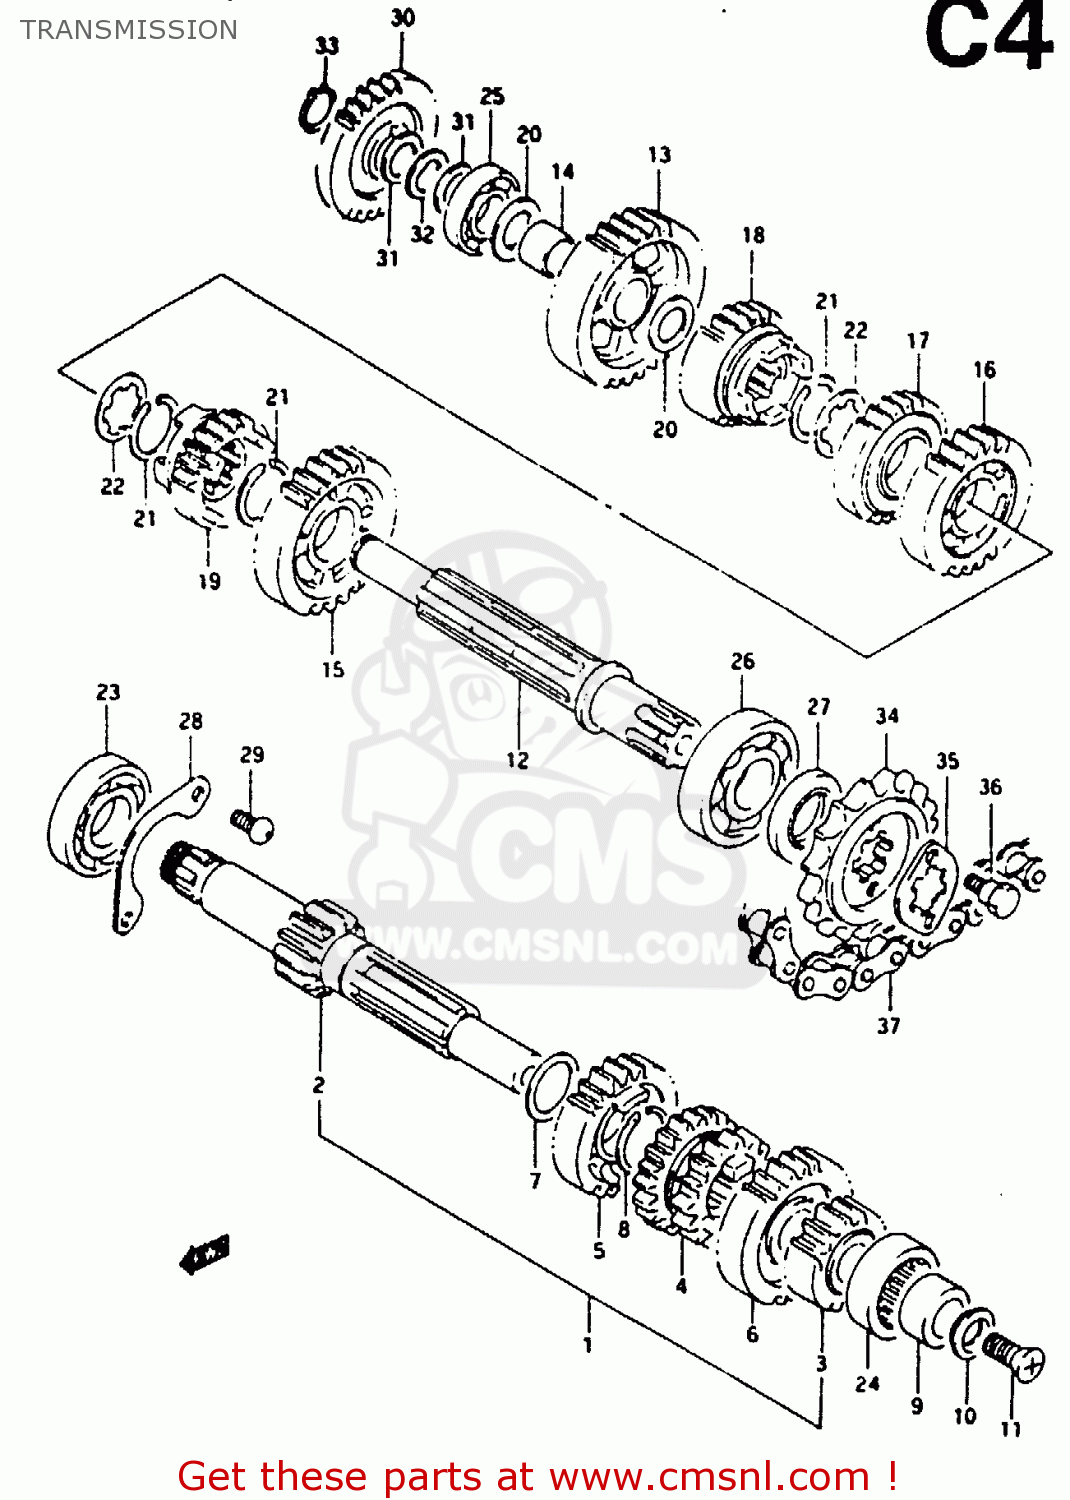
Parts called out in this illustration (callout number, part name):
1	COUNTER SHAFT
2	SHAFT,COUNTER(NT11)
3	GEAR,2ND DRIVE(NT:14)
4	GEAR, 3RD/4TH DRIVE (NT:15/21)
5	GEAR,5TH DRIVE(NT:24)
6	GEAR, 6TH DRIVE (NT:24)
7	WASHER
8	CIRCLIP
9	RACE,CNTR SHAFT L BRG INNER
10	RETAINER,CNTR SHAFT L BEARING
11	SCREW
12	SHAFT,DRIVE
13	GEAR, 1ST DRIVEN (NT:29)
14	BUSH(15X18X13)
15	GEAR,2ND DRIVEN(NT:26)
16	GEAR,3RD DRIVEN(NT:20)
17	GEAR,4TH DRIVEN(NT:23)
18	GEAR,5TH DRIVE
19	GEAR, 6TH DRIVEN (NT:20)
20	WASHER,THRUST
21	CIRCLIP
22	WASHER,LOCK
23	BEARING(20X47X10.5)
24	BEARING,20X32X1
25	BEARING(15X35X8)
26	BEARING(20X52X12.5)
27	OIL SEAL (20X35X5)
28	RETAINER,CNTR SHAFT BEARING
29	SCREW 6X12
30	GEAR,KICK STARTER IDLE
31	THRUST WASHER
32	WAVE WASHER
33	CIRCLIP
34	SPROCKET,ENGINE(NT:16)
35	PLATE
36	BOLT(6X13)
37	CHAIN ASSY, DRIVE (DID 428VCA*130LE)
